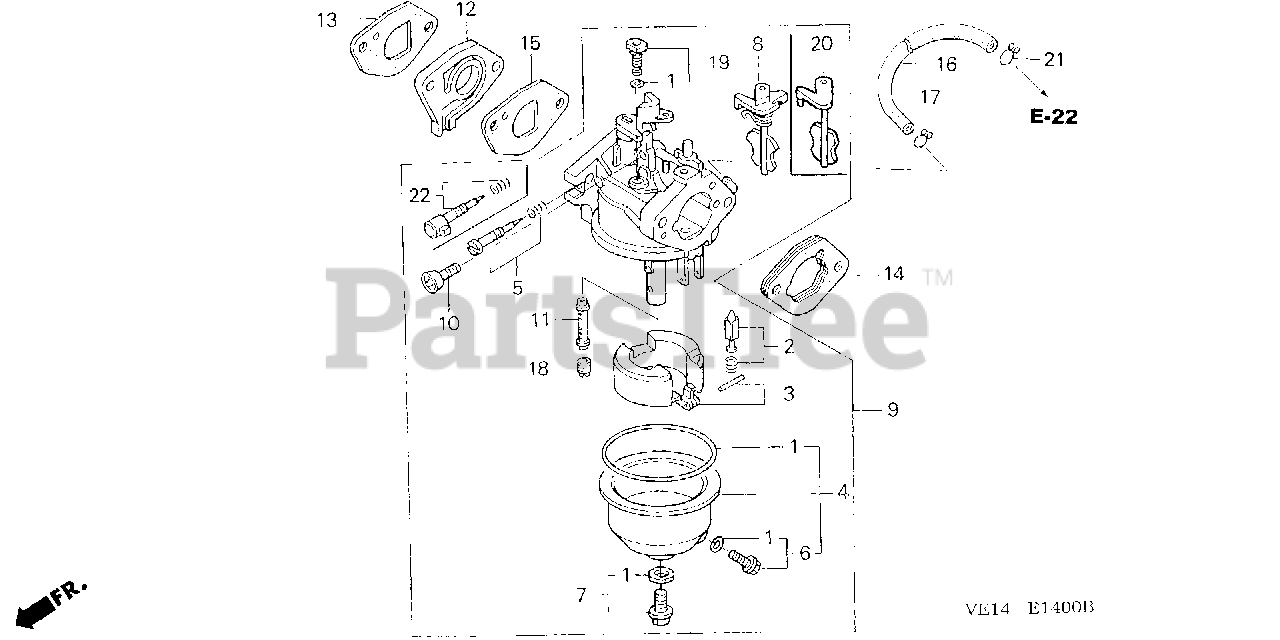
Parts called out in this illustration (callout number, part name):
1	GASKET SET
2	VALVE SET, FLOAT (SEAT NOT INCLUDED)
4	CHAMBER SET, FLOAT
6	SCREW SET, DRAIN
7	SCREW SET
8	CHOKE SET
9	CARBURETOR ASSY. (BE52B A)
9	CARBURETOR ASSY. (BE52B D)
10	SCREW, THROTTLE STOP
11	NOZZLE, MAIN
12	INSULATOR, CARBURETOR
13	GASKET, CARBURETOR
14	SPACER, CARBURETOR
15	GASKET, CARBURETOR
16	TUBE, FUEL VALVE (170MM)
16	BULK HOSE, FUEL (4.5X3000) (4.5X165)
17	CLIP, TUBE (B8)
18	JET, MAIN (#50)
18	JET, MAIN (#52)
18	JET, MAIN (#55)
19	JET SET, PILOT (#35)
20	CHOKE SET
21	CLIP, TUBE (B8)
